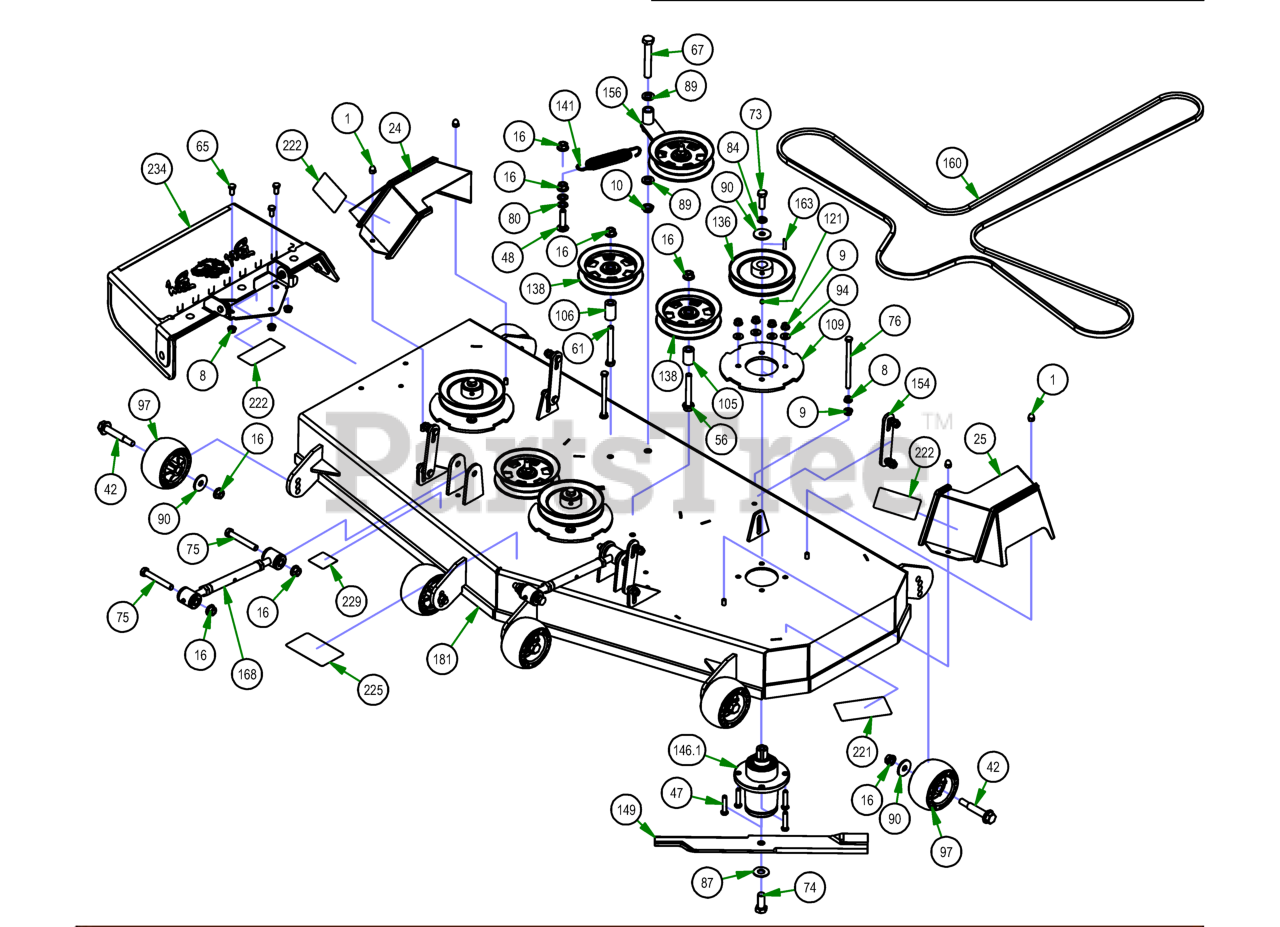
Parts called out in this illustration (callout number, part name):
1	5/16-18 ACORN NUT HIGH-CROWN ZC
8	3/8-16 HEX SERRATED FLANGE NUT HARD/ZINC
9	3/8-16 NYLON INSERT FLANGE LOCKNUT (GR.F) ZINC
10	5/8-11 NYLON INSERT JAM LOCKNUT ZINC
16	1/2-13 NYLON INSERT FLANGE LOCKNUT ZINC
24	2021 Maverick 54”/60” RH Pulley Cover
25	2021 Maverick 54”/60” LH Pulley Cover
42	Deck Wheel Bolt
47	3/8-16 X 1-3/4 HEX C/S (GR.5) ZC
48	1/2-13 X 2 CARRIAGE BOLT ZINC
56	1/2-13 X 3-1/2 HEX FLANGE BOLT (GR.8) ZINC
61	1/2-13 X 4 HEX CAP SCREW (GR.8) ZINC YELLOW
65	3/8-16 X 3/4 HEX CAP SCREW (GR.5) ZINC
67	5/8-11 X 4 HEX CAP SCREW (GR.8) ZINC YELLOW
73	1/2-20 X 1-1/2 HEX CAP SCREW (GR.5) ZINC
74	5/8-18 X 1-1/2 HEX CAP SCREW (GR.8) ZINC YELLOW
75	1/2-13 X 3-1/2 HEX CAP SCREW (GR.5) ZINC
76	3/8-16 X 5-1/2 HEX CAP SCREW (GR.5) ZINC
80	.517 SQ WDTH ID X .937 OD X .060 THICK F/W PHOS/OIL
84	1/2 SPLIT LOCKWASHER (GR.8) ZINC/YELLOW
87	5/8 USS FLAT WASHER (1-3/4" OD) GR.8 ZINC YELLOW
89	.635 ID X 1.120 OD X .140 THICK FLAT WASHER NYLON
90	1/2 BELLEVILLE WASHER (1-5/8 OD X .140 THK) ZINC
94	5/16 USS FLAT WASHER (7/8 OD) ZINC
97	Deck Wheel
105	.502 ID X .750 OD X 1.500 Long Spacer
106	1 3/4" Pulley Spacer
109	Deck Spindle Support Plate
121	5/16-24 X 1/4 SOCKET SET SCREW (CUP PT) PLAIN
136	6 1/4" Drive Pulley
138	5-3/4 Idler Pulley
141	Deck Idler Spring
146	Spindle Assembly
149	60" High Lift Fusion Blade
154	Deck Hanger Assembly
156	2017 MZ/ZT Deck Idler Assembly
163	1/4 X 1 SQ MACHINERY KEY 1018 STL PLN
168	2018 Maverick Turnbuckle (Top Link)
181	2017 60" ZT Deck Welded Assembly
221	2018 60" Deck Decal
222	Danger Decal-Spindle/Discharge
225	Deck Belt Route Decal
229	Deck Impact Patent Decal 9591803
234	Discharge Chute Assembly
